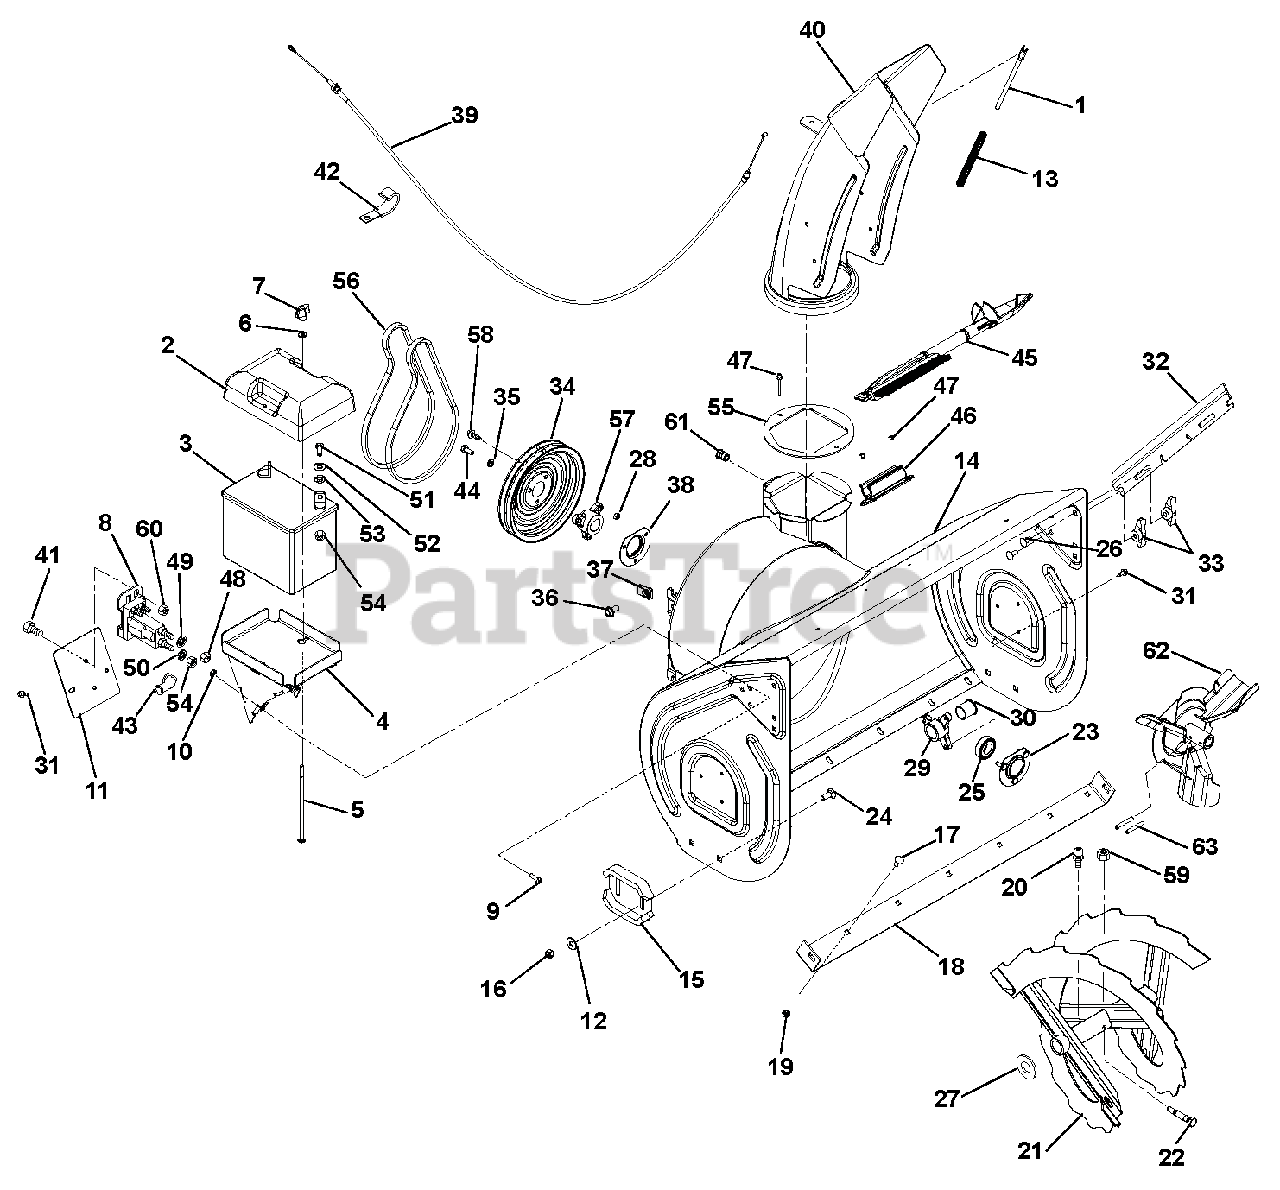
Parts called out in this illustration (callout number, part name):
1	ROD, DEFLECTOR CAP
2	COVER, BATTERY
4	TRAY, BATTERY-W/CLIPS
5	@BLT-RDHDSQNK .25-20X7.00 G2YZ
6	@WSHR-FL-STL.281X.62X.065 YWZC
7	KNOB, WING - .25-20 UNC
8	SOLENOID
9	BLT-HEX .25-20X.75 HWH YZ GR5
10	NUT-RTNR .25-20X.56
11	COVER, SOLENOID
12	@WSHR-FL-STL.438X1.00X.083 YWZ
13	SG-COMP .08X.40X6.50 14#/IN
14	BLOWER HOUSING W/DECAL 28"
14	BLOWER HOUSING W/DECAL 32"
14	BLOWER HOUSING W/DECAL 32" BAT
14	BLOWER HOUSING W/DECAL 36"
14	BLOWER HOUSING W/DECAL 36" BAT
15	RUNNER, SKID SHOE
16	@NUT-LK-CTR .38-16 YWZC
17	BLT,RDSHHDSQSHNK .31-18X.62 YZ
18	BLADE, SCRAPER-28"
18	BLADE, SCRAPER-32"
18	BLADE, SCRAPER-36"
19	@NUT-LK-TOP-FLG .31-18 YWZC
20	ZERK,FITTING .25X.125 DRIVE IN
21	RAKE, LH-28"(1 ID X 15.75 OD)
21	RAKE, RH-28"(1 ID X 15.75 OD)
21	RAKE, LH-32"(1 ID X 15.75 OD)
21	RAKE, RH-32"(1 ID X 15.75 OD)
21	RAKE, LH-36" (1 ID X 15.75 OD)
21	RAKE, RH-36"(1 ID X 15.75 OD)
22	SHEAR BOLT SERVICE ASSEMBLY
23	BEARING FLANGE
24	@BLT-RDHDSHSQNK.38-16X1.0 G5YZ
25	BRG-BALL .876X1.75X.50 RSTFP
26	@BLT-RHDSSQNK .31-18X.75 G5YZ
27	WSHR-FL-STL 1.010X1.505X.062YZ
28	@NUT-LK-CTR .25-20 YWZC
29	BUSHING, RAKE SHAFT 1"
30	BSHG-FLG SPLIT NYLINER 1.0" HP
31	SCR-TAP .25-20X.50 HWH TR YWZ
32	CUTTER, DRIFT
33	KNOB,WING .31-18 UNC NYL/TALC
34	PULLEY, SPIN FORM DUAL GROOVE
35	WSHR-LK .312X.097 HVY YWZC
36	BLT-SERHFWH .38-16X.75 YWZC
37	NUT-RTNR .375-16X.37
38	BEARING FLANGE
39	CABLE, DEFLECTOR-COATED
40	CHUTE, DISCHARGE-W/DEFLECTOR
40	CHUTE, DISCHARGE W/CAP & DECAL
41	@BLT-HEX .25-20X.50 GR5 YWZC
42	J-CLAMP
43	BOOT, EYELET TERMINAL
44	BLT-HEX .31-24X.75 YWZC GR5
45	DEVICE, SNOW CLEAN OUT W/BRUSH
46	MOUNT, SNOW CLEAN OUT
47	RVT-POP .187 YZ
48	NUT-JAM .31-24 YWZC
49	WSHR-LOCK INT .31 YWZC
50	@WSHR-LK-EXT.262X.502X.026YWZC
51	@BLT-HEX .25-20X.75 GR5 YWZC
52	WSHR-FL-STL .265X.50X.087YWZC
53	@WSHR-LK .25X.062 REG YWZC
54	@NUT-HEX .25-20 YWZC
55	BAFFLE, DISCHARGE NECK
56	V-BELT, HA-RAW EDGE (SET)
57	PULLEY HUB, D-BORE .87 PRO
58	@SCR-TAP .31-18X.50 HWH TR YWZ
59	@NUT-LK-CTR .31-18 YWZC
60	@NUT-LK-CTR .25-20 YWZC
61	NUT, THREADED INSERT .38-16
62	IMPELLER, 3 BLADE-14"
63	PIN-ROLL .250X1.75
